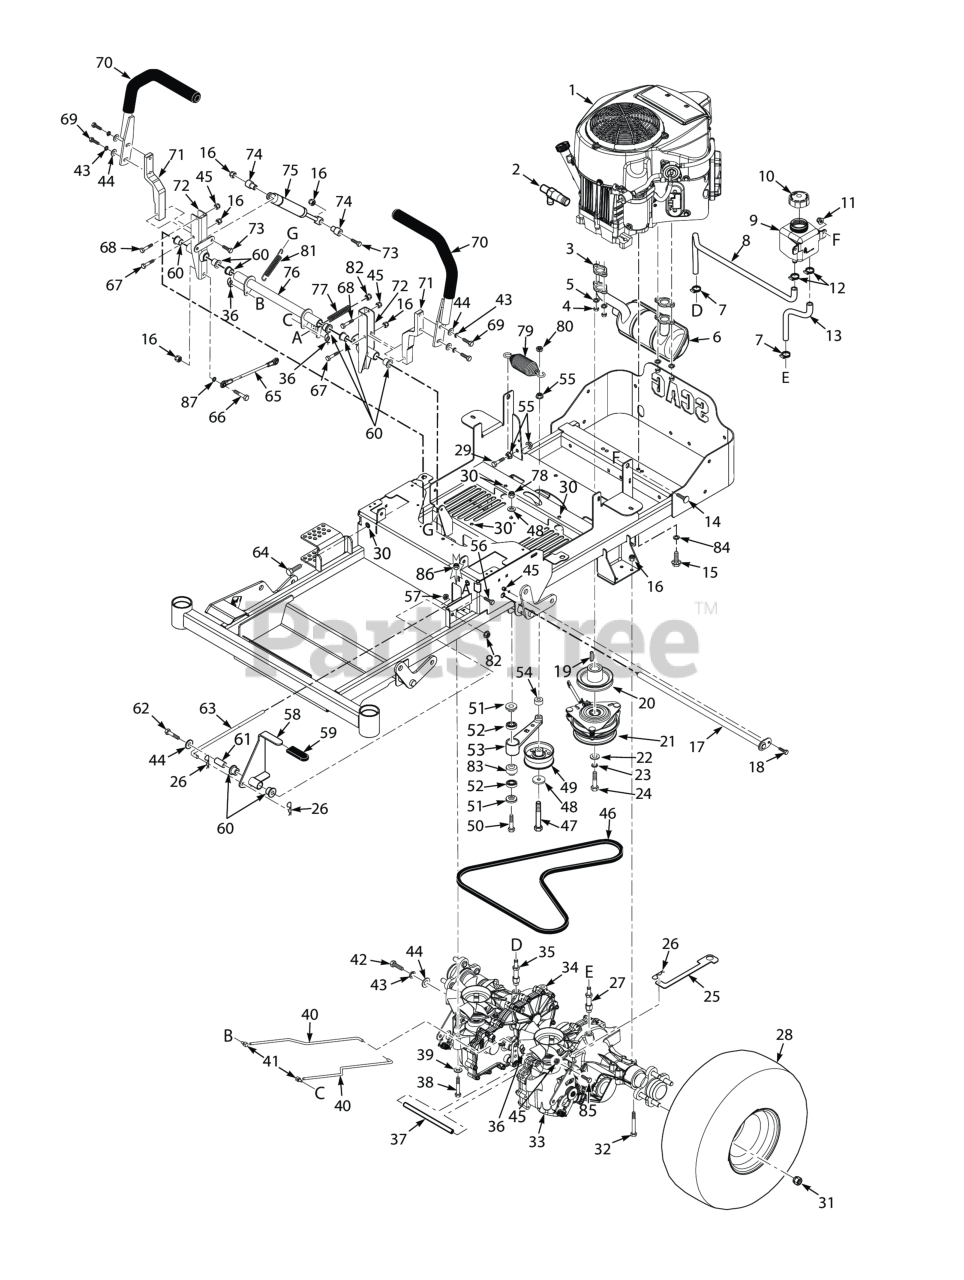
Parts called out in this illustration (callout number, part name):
1	Engine, Kawasaki - FR600V
2	Oil Drain, Kawasaki
3	Gasket, Exhaust
4	Nut, M8 x 1.25 Hex Special
5	Lockwasher, M8 Spring (Kawasaki)
6	Muffler, Kawasaki FR/FS600V
7	Clamp, .69" Max. / .25" Min. Dia.
8	Hose, RH Transaxle
9	Reservoir Assembly
10	Cap, Hydraulic Tank
11	Nut, Flanged Elastic Stop 1/4-20
12	Clamp, Cable 3/4" I.D.
13	Hose, LH Transmission
14	Serr. Fl. Hex Head CPSCR, 1/4-20 x 3/4"
15	Bolt, Hex Head 3/8-16 x 1-1/4", Kawasaki FX / FS
16	HEX NUT, ELASTIC STOP LOCK, 5/16-18
17	Shaft Weldment, Control Arm
18	BOLT, HEX HEAD, 1/4-20 X 5/8
19	Key, 1/4 x 1/4 x 1.25" Pulley Mtg.
20	Pulley, 4-1/2" - 1" Bore
21	Electric Clutch Assembly
22	Flatwasher, 7/16-.469 x 1.75 x .25 (48, 52)
23	Lockwasher, 7/16� Spring
24	Bolt, Hex Head 7/16-20 x 3¼" w/Patch
25	Lever, Dump Valve
26	HAIR PIN, .08 DIAMETER X 1-3/16"
27	Fitting, 9/16" O-Ring x 3/8" Hose
28	Wheel Assembly, 20 x 8.0-10
28	Rim W/Valve Stem 10 x 5.0
28	Tire, 20 x 8.0-10
29	Bolt, Hex Head 3/8-16 x 1-1/2" Grade 8 Black
30	Threaded insert, Hex Head (Pressed)
31	Wheel Nut, 1/2-20 x 13/16
32	Bolt, Hex Head, 5/16-18 x 2.75 Zinc.
33	Transaxle, LH- ZT-2800
34	Transaxle, RH- ZT2800
35	Fitting, O-Ring 9/16 Hose
36	Pin, Rue Cotter 3/8" Diameter
37	Spacer, Axle
38	BOLT, HEX HEAD, 5/16-18 X 2-1/4
39	Flatwasher, 5/16-.375 x .875 x .083 (35BV & 37BV-EFI)
40	Rod, Brake
41	Joint, Swivel
42	Bolt, Hex Head 3/8-16 x 2-1/4" - 61"
43	Lockwasher, 3/8" Spring, Kawasaki FX / FS
44	Flatwasher, 3/8" Special (.391 x .938 x .105)
45	HEX, NUT, ELASTIC STOP LOCK, 1/4-20
46	Belt, Transmission SZL-36
47	Capscrew, Hex Head 3/8-16 x 3-3/4"
48	Flatwasher, 3/8 (.391 x .938 x .105 HD) Grade 8
49	Pulley, 3-1/2" Dia.
50	Bolt, Hex Head 3/8-16 x 3" - 52"
51	Spacer, Controls
52	BEARINGS, BALL, NEUTRAL RETURN
53	Trans. Idler Arm Assy. (Includes 24, 79)
54	Spacer, Idler Pulley - SFZ61
55	NUT, 3/8-16 SERRATED FLANGE HEX HEAD
56	Bolt, Hex Head 5/16-18 x 1-1/2" (Right Front Engine Mounting, Briggs and Kohler Only)
57	Nut, Flange Elastic Stop Nut, 3/8-16
58	Brake Lever Assembly (INCL 59,60)
59	Grip, Brake Handle
60	Bearing
61	Pivot, Brake Lever
62	Capscrew, Hex Head 3/8-16 x 2-1/2"
63	Rod, Upper Brake Linkage
64	Bolt, Hex Head 3/8-16 x 3.0
65	Linkage Assembly, Steering
66	Bolt, 5/16 - 18 x 1 - 1/4" Hex Head
67	Bolt, Hex Head 5/16-18 x 1-1/2" - Front
68	Bolt, Hex Head, 1/4-20 x 1-1/4"
69	Bolt, Hex Head, 3/8-16 x 1 Gr. 5
70	Handlebar W/ Grip, SZL-36
71	Lever, Control Arm
72	Control Arm Weldment, SZL-36
73	Bolt, Hex Head 5/16-18 x 2-1/2" (x3) (35BV & 37BV-EFI)
74	Spacer, Pump Dampener
75	Damper, Steering
76	Bellcrank Assembly, Brake
77	Spring, Brake
78	HEX NUT, ELASTIC STOP LOCK, 3/8-16
79	Spring, Transmission Drive
80	Bolt, Hex Head 3/8-16 x 1" Ser. Flg.
81	Spring, Deck Latch
82	Nut, Flange Elastic Stop Nut, 3/8-16
83	Spacer, Bearing
84	Lockwasher, 3/8" Spring, Kawasaki FX / FS
84	Lockwasher, 5/16" Ext. Tooth (Kohler x1)
85	Bolt, Hex Head, 1/4-20 x 1-1/2"
86	Nut, Flange Head Elastic Stop 5/16-18
87	Lockwasher, 5/16 (.317 x .586 x .078) Helical Spring
